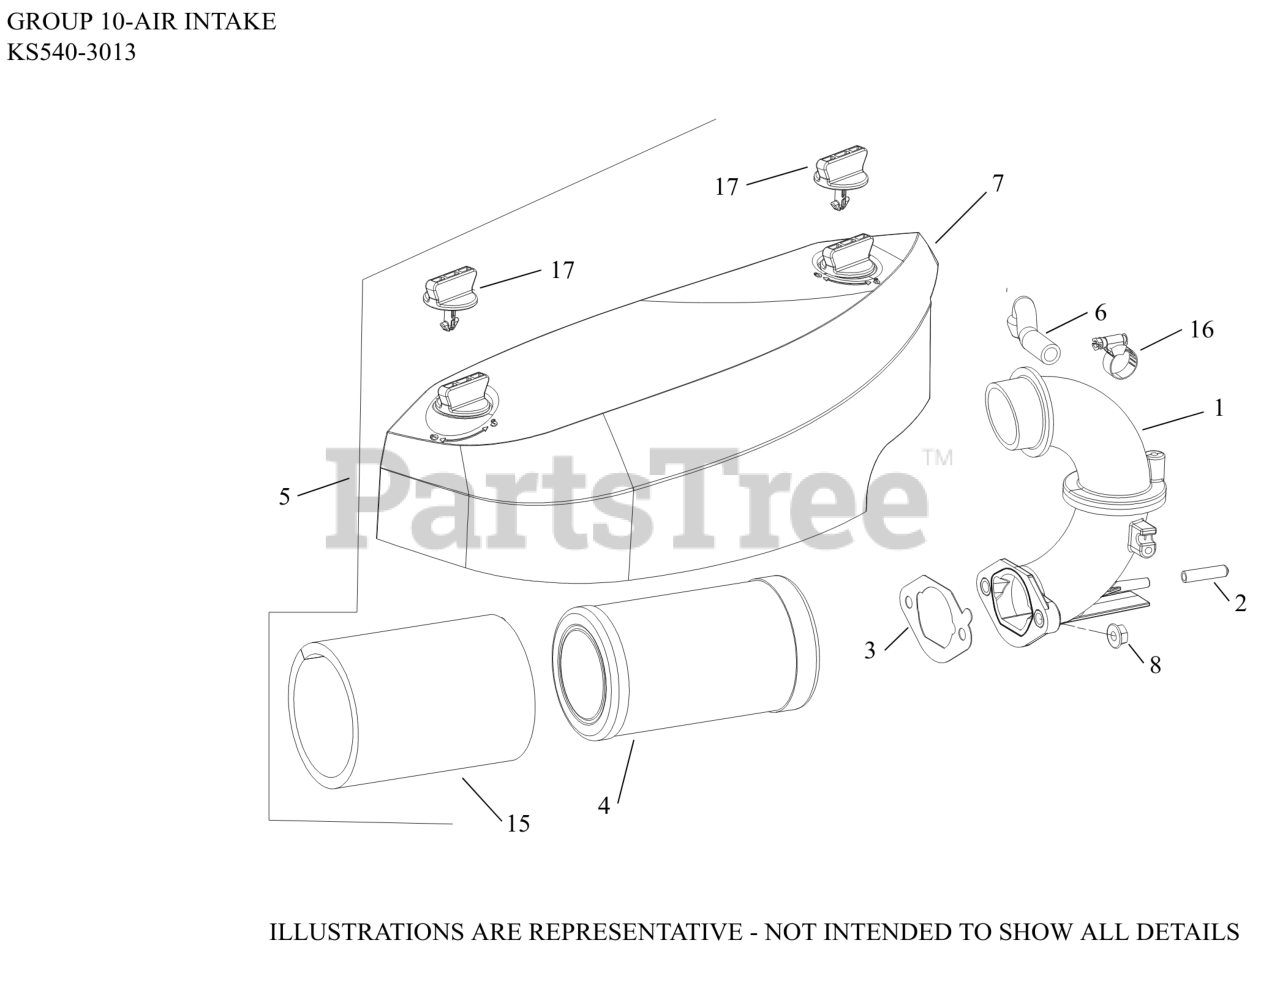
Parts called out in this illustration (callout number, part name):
1	ADAPTER, AIR CLEANER ASSY
2	CAP, MASKING
3	GASKET, CARBURETOR
4	ELEMENT, AIR FILTER
5	AIR FILTER KIT (STD)
6	HOSE, BREATHER
7	COVER, AIR CLEANER ASSY
8	NUT, FLG M6X1.0
15	ELEMENT, PRE-CLEANER
16	CLAMP, HOSE (KM)-USE 25 237 31-S
17	KNOB, AIR CLEANER COVER
